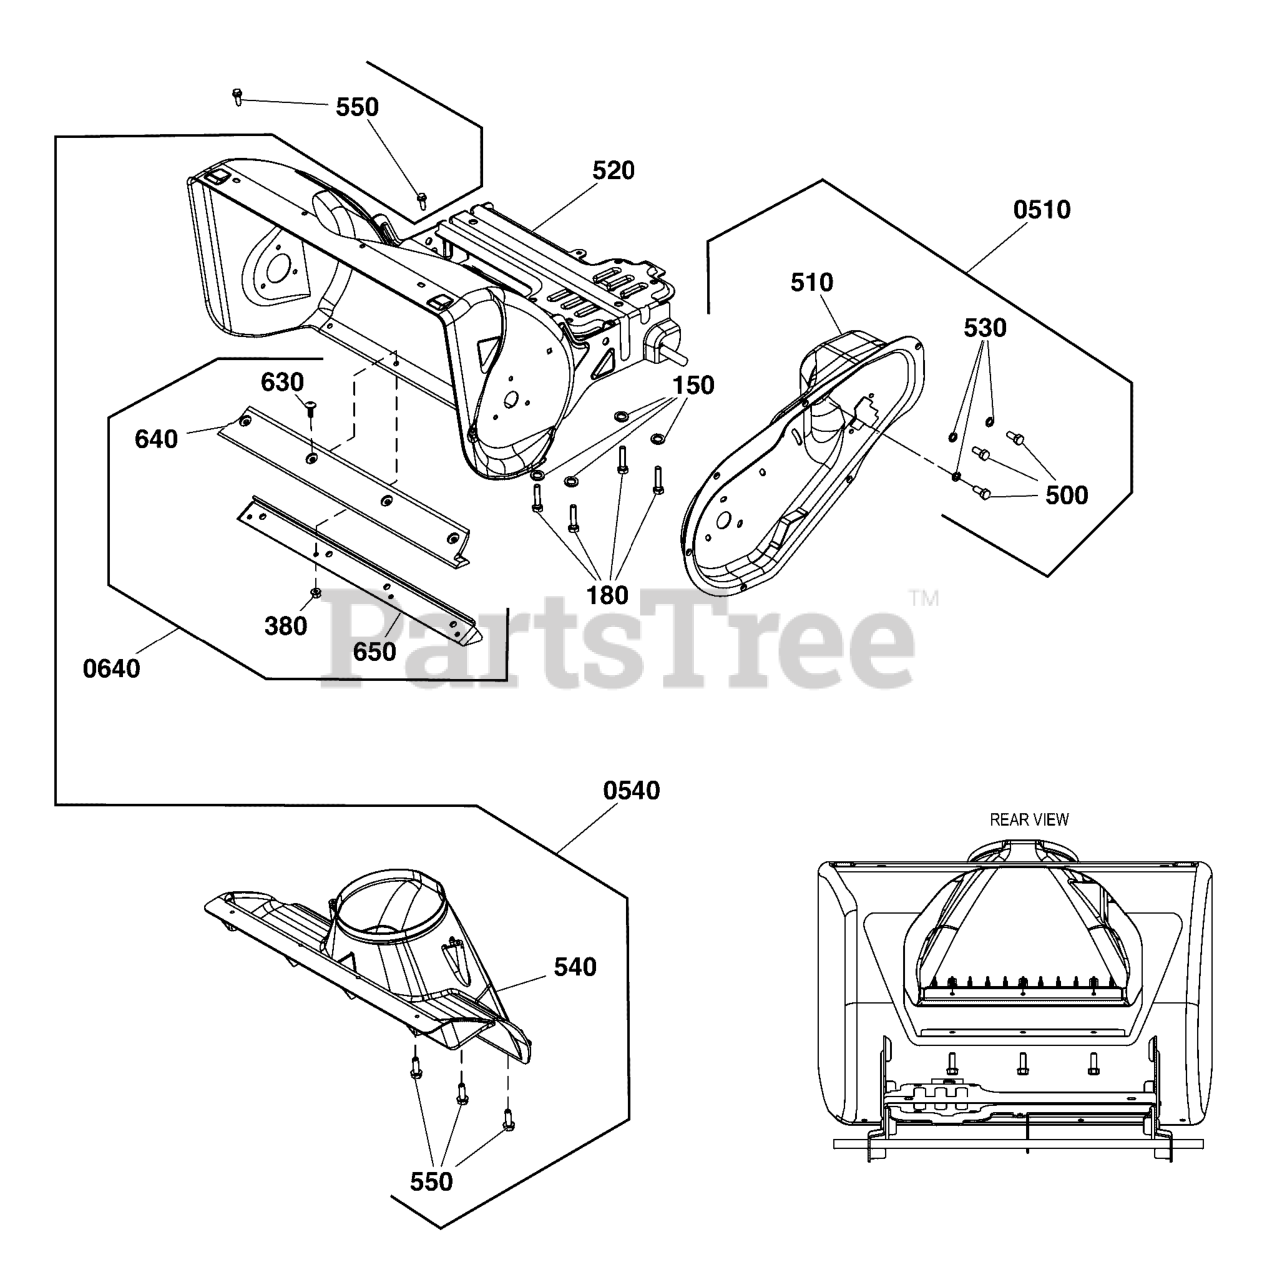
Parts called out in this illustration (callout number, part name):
150	WASHER, M10, Split Lock
180	SCREW-HEX WSHR HD TAPTT 3/8-16X1.250, ZC
380	NUT, 1/4-20, Nylon Hex, CZ
500	CAPSCREW, Hex Head, 5/16-24 x 5/8
0510	KIT, DRIVE HOUSING
510	HOUSING, Drive
520	HOUSING, Auger
530	WASHER, Split Lock, .32 x .58 x .08
0540	KIT, CHIMNEY
540	CHIMNEY
550	SCREW, 1/4-15X3/4, Self-Tapping, BZ
630	SCREW, 1/4-20 X 5/8
0640	KIT-SCRAPER BAR
640	BAR, Scraper, Robolon
650	SUPPORT, Scraper Blade
